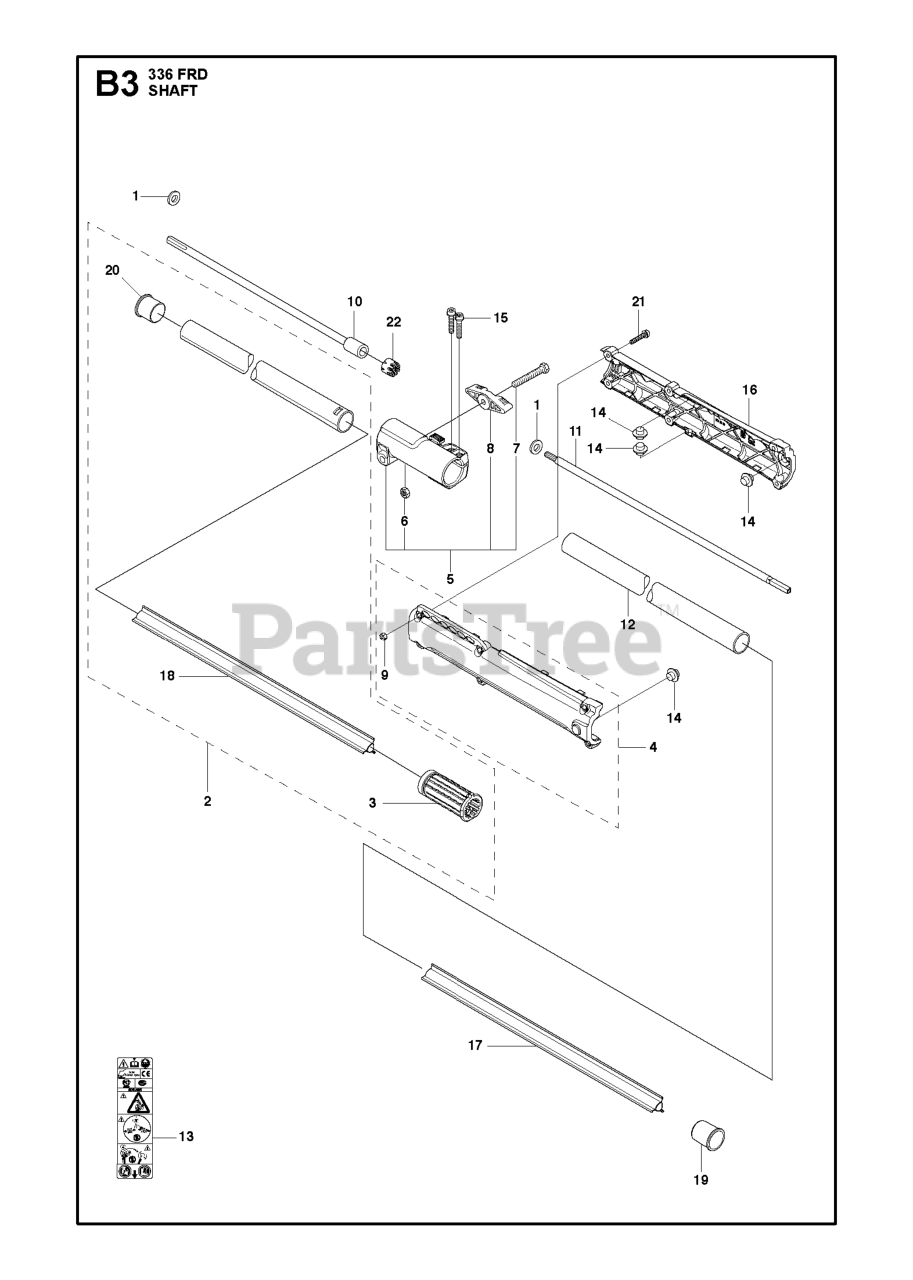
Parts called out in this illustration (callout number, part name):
4	WEAR PROTECTION
13	LABEL WARNING TRIMMERS AND BRU
14	VIBRATION ABSORBER
16	WEAR PROTECTION
17	GUIDE UPPER L=576
18	GUIDE LOWER L=735
20	PLUG
